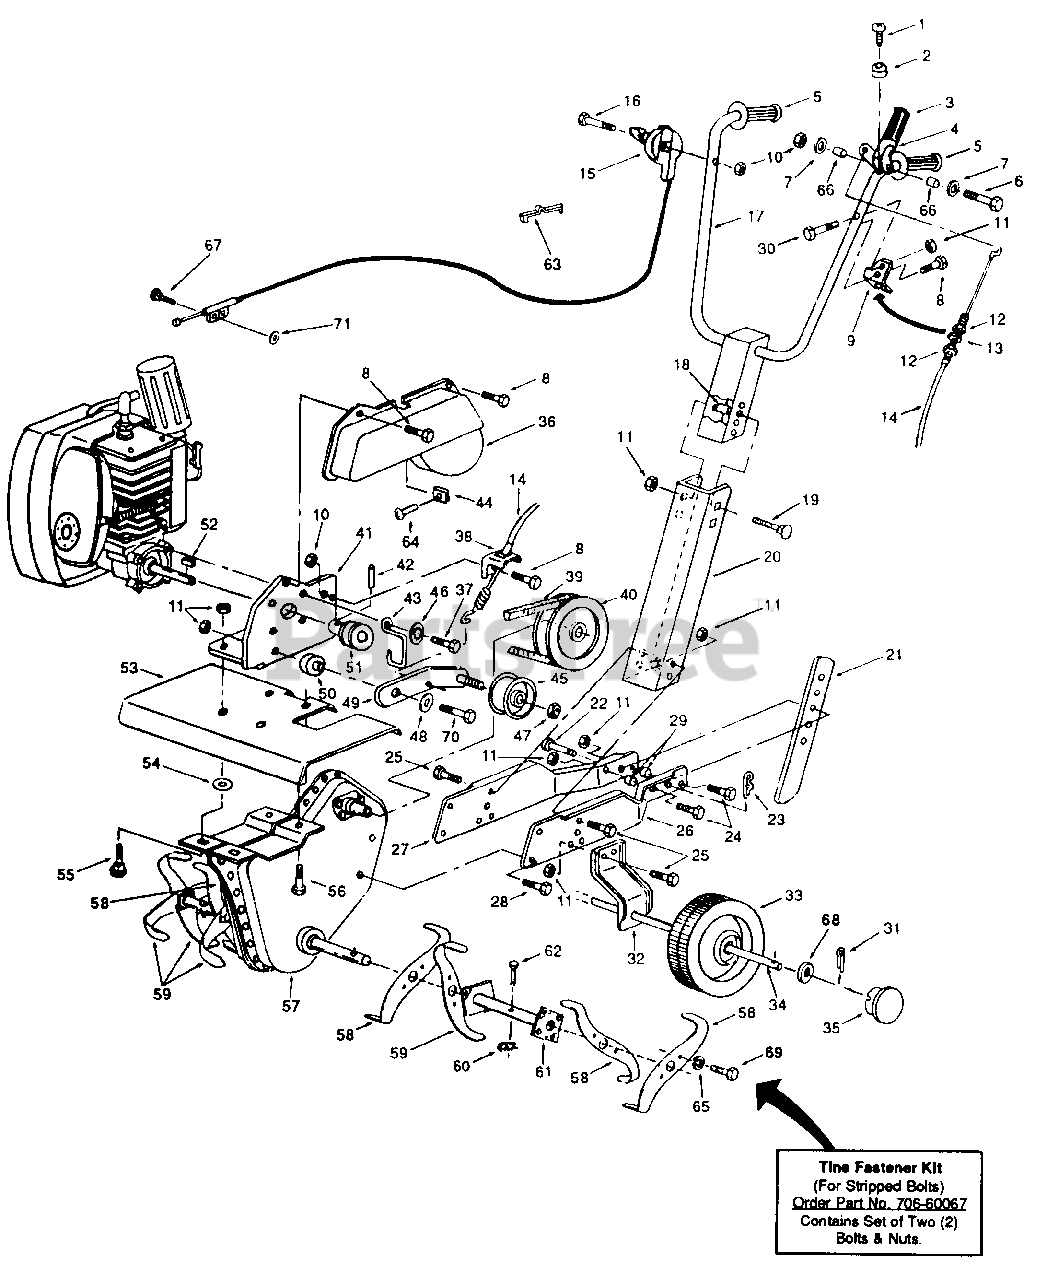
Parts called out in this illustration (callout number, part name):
1	Tap Scr. #10-16 x 1/2
2	Rubber Bumper
3	Vinyl Grip
5	Handle Grip
6	Hex Bolt 1/4-20 x 2"
7	Fl-Wash. 1/4" I.D.
8	Hex Tap Scr. 1/4-20 x 1/2
9	Cable Bracket
10	Lock Nut 1/4-20 Thd.
11	Lock Nut 5/16-18 Thd.
12	Hex Jam Nut 5/16-24 Thd.
13	L-Wash. 5/16" I.D.
14	Clutch Control Cable
15	Throttle Control
16	Hex Bolt 1/4-20 x 1-1/2"
19	Carr. Bolt 5/16-18 x 2-1/2"
23	Hairpin Cotter
24	Hex Bolt 5/16-18 x 1"
25	Hex Bolt 5/16-18 x 5/8"
29	Spacer
30	Hex Bolt 5/16-18 x 1-1/4"
31	Cotter Pin
34	Axle Wheel
35	Hub Cap
36	Belt Cover
37	Hex Bolt 1/4-20 x 5/8"
38	Bracket Clutch Lever
39	V-Belt
40	Pulley Chain Case
41	Plate Engine Mounting
42	Set Screw 5/16-18 x 3/8"
43	Belt Retainer
44	Clip Tinnerman
45	Flat Idler Pulley
46	Int. L-Wash. 1/4" I.D.
47	Hex Jam Thd. L-Nut 318-24
48	Fl-Wash. 5/16' I.D.
49	Idler Arm Ass'y.
50	Pivot Spacer
51	Engine Pulley
52	Square Key 1/8 x 3/4"
53	Tine Shield (Red)
54	Spacer
55	Carriage Bolt 5/16-18 x 1"
56	Hex Bolt 5/16-18 x 3/4"
57	Chain Case Ass'y. Comp.
58	R.H. Tine Blade
59	L.H. Tine Blade
60	Hairpin Cotter
61	Adapter Ass'y. Tine
62	Clevis Pin
63	Cable Tie Plastic
64	Scr. #10-16 x 3/4 Sems
65	L-Wash. 1/4" I.D.
66	Spacer
67	Screw
68	Fl-Wash. 3/8" I.D.
69	Tap Scr. 1/4-20 x 1/2"
70	Hex Bolt 5/16-18 x 1-1/2"
71	Fl-Wash.
